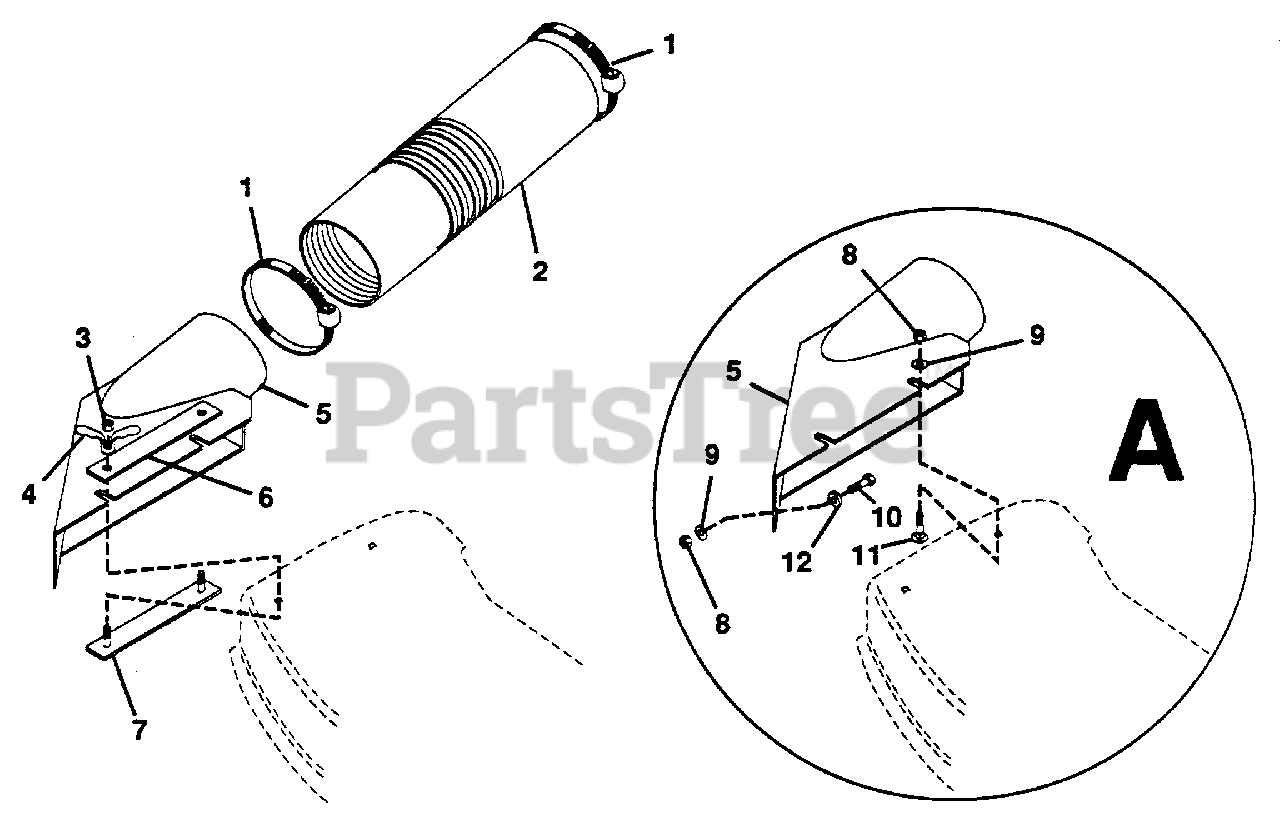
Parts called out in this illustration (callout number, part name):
1	Clamp
2	Hose, Mower to Blower
3	Nut, Lock 3/8-16
4	Nut, Wing 3/8-16
5	Boot, 40"
6	Plate, 40" Boot
7	Weldment, 40" Boot Clamp
8	Nut, Lock 3/8-16
9	Washer, Flat .406x.812x.065
10	Bolt, Hex 3/8-16x1.00(50" Mower Only)
11	Bolt, Carriage 3/8-16x.75
12	Bushing(40" Mower Only)
